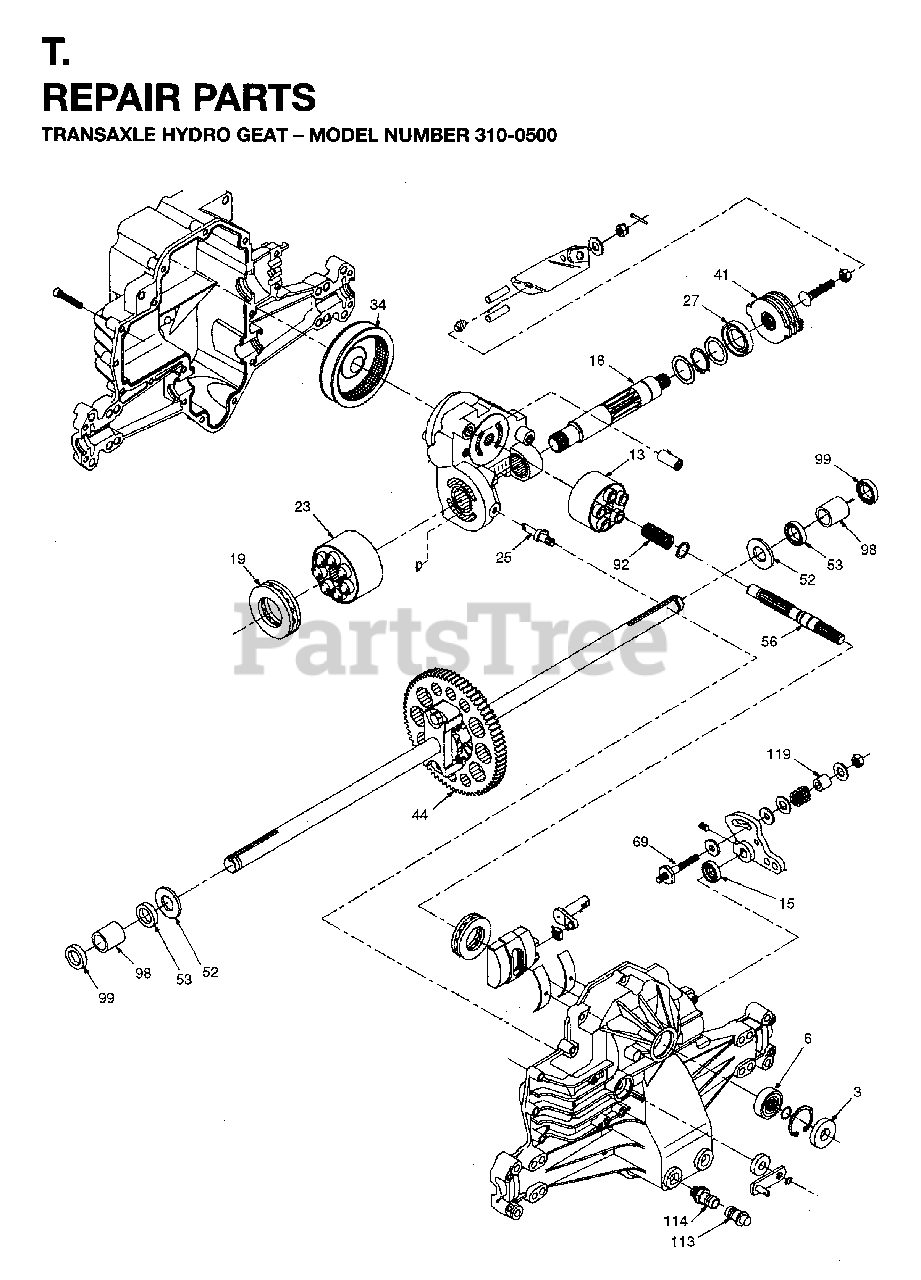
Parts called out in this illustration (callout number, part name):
6	BALL BEARING
13	BLOCK, CYL ASSY
19	THRUST BEARING
23	BLOCK, CYL ASSY
25	BYPASS ACTUATOR
34	ELEMENT, OIL FILTER
41	BRAKE ROTOR
44	DIFFERENTIAL ASSEMBLY
52	WASHER.HYDRO-GEAR
53	SEAL.HYDRO.45076
56	INPUT SHAFT
69	STUD 5/16-24
98	BEARING SLV 50137
99	SEAL, WIPER
113	CAP, VENT ASSY
114	O-RING.ASM.70110
119	SPACER
